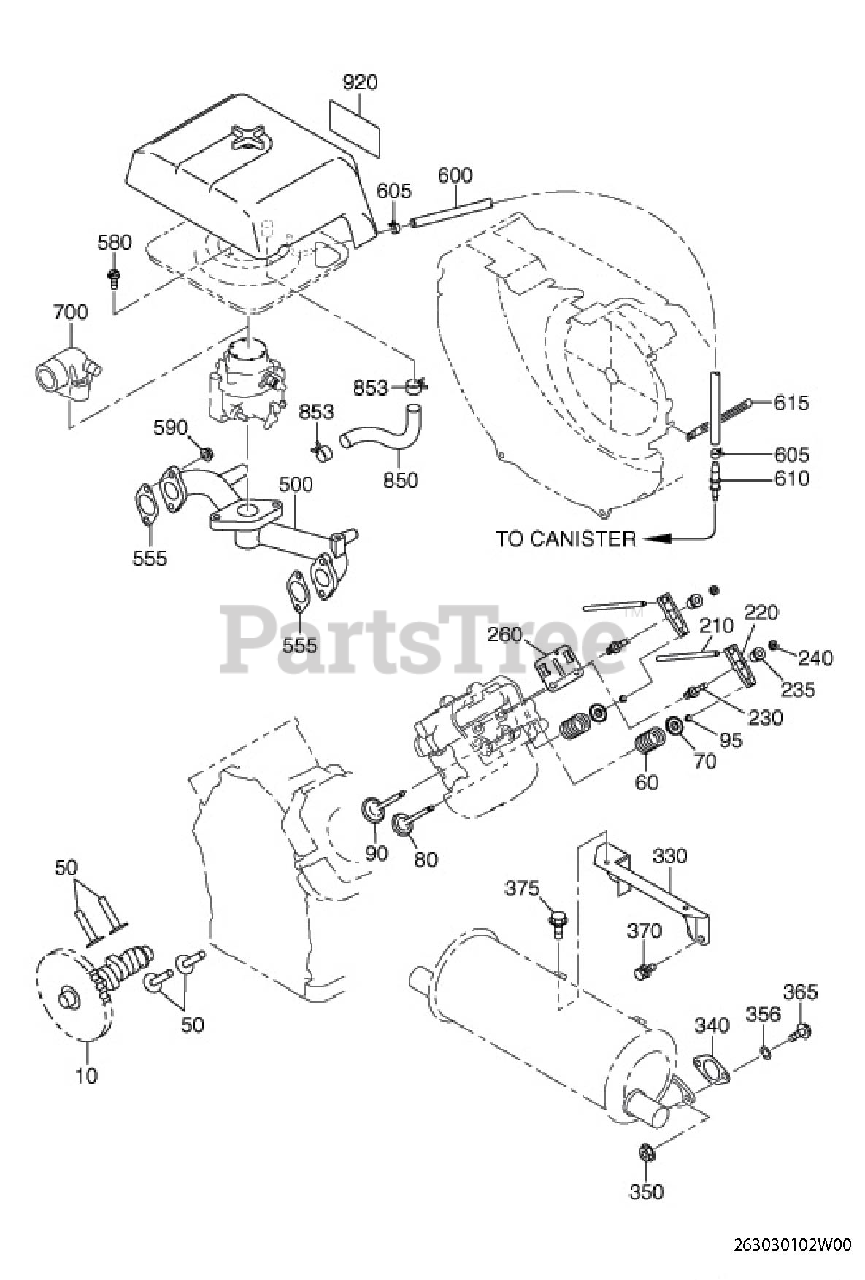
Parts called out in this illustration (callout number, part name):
10	CAM SHAFT
50	TAPPET
60	VALVE SPRING
70	SPRING RETAINER
240	NUT
330	BRACKET(MUFFLER)
340	GASKET CP (MUFFLER)
350	FLANGE NUT
370	BOLT AND WASHER AY
375	FLANGE BOLT
500	INTAKE MANIFOLD
555	GASKET(IN MANIFOLD)
580	FLANGE BOLT
590	FLANGE NUT
850	RUBBER PIPE
853	HOSE CLAMP
920	LABEL(TRADE MARK)
